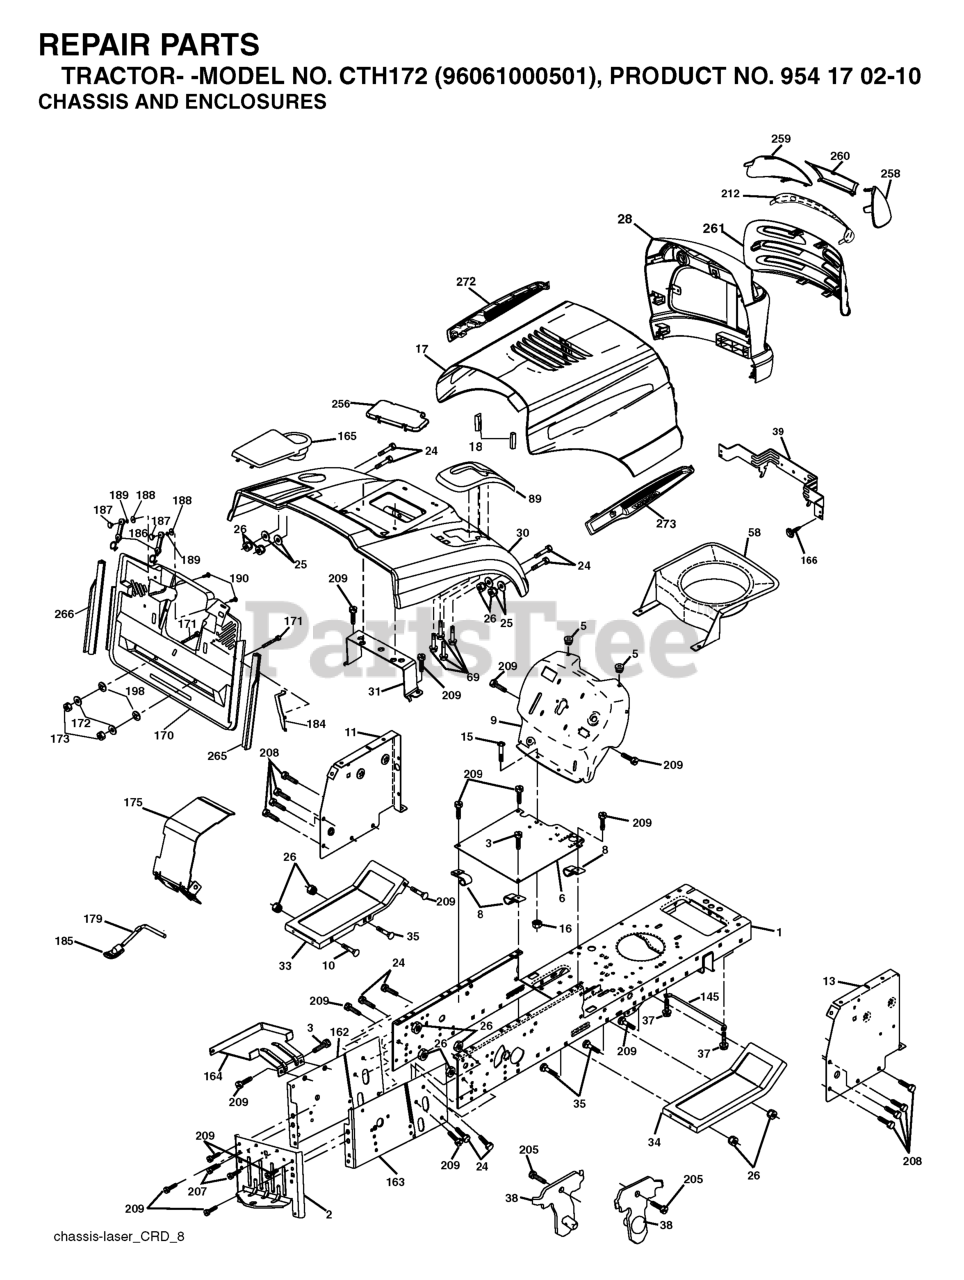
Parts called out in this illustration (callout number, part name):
2	DRAWBAR
3	SCREW 3/8-16X3/4
5	BUMPER.RUBBER.HOOD
6	PLATE
8	CLIP,INSULATOR
10	BOLT D
11	PANEL.DASH.LH.LTX
13	PANEL ASM, DASH RH
15	Screw, Machine, Truss Head 5/16-18 UNC x 3/4
16	NUT
17	VENT.HOOD.LASER.III
18	BUMPER.HOOD.LARGE.1.75"
24	BOLT
25	WASHER
26	NUT
30	CONSOLE.CRD.AUTO.GRY
31	BRACKET SUPPORT FENDER
33	FOOTREST PNT LH
34	FOOTREST PNT RH
35	BOLT
37	Screw 5/16-18 x 1/2 Hex, Self Tapping 5/16-18 x 1/2
38	BRACKET ASM PIVOT MOWER REAR
39	BRACKET PIVOT LASER
69	SCREW.HI-LO.CONSOLE
89	CONSOLE.CRD.AUTO.GREY.2005
145	ROD PIVOT CHASSIS/HOOD
162	BRACKET
163	BRACKET EXTEN CHASSIS RH CRD
165	RP.COVER.BATTERY.CRD.GREY
166	SCREW
171	BOLT
172	WASHER
175	DOOR TRAP
179	.WITCH.FULL BAGGER.INDICATOR
184	BRACKET.ACTUATOR.BAGGER.SRD
186	LATCH ASSY
187	WELDNUT
189	LOCKWASHER #10
190	SCREW
205	SCREW LT
207	SCREW, 5/16-18 X 1/2
208	SCREW 3/8-16X1/2
209	SCREW, 3/8-16X3/4
212	INSERT.LENS.REFLECTIVE
256	COVER FENDER CRD
258	LENS LH
259	LENS LH
260	COVER.LENS.HUSQ.LASER
265	SEALING
266	SEALING
272	VENT.HOOD.LASER.
273	VENT.HOOD.LASER.
